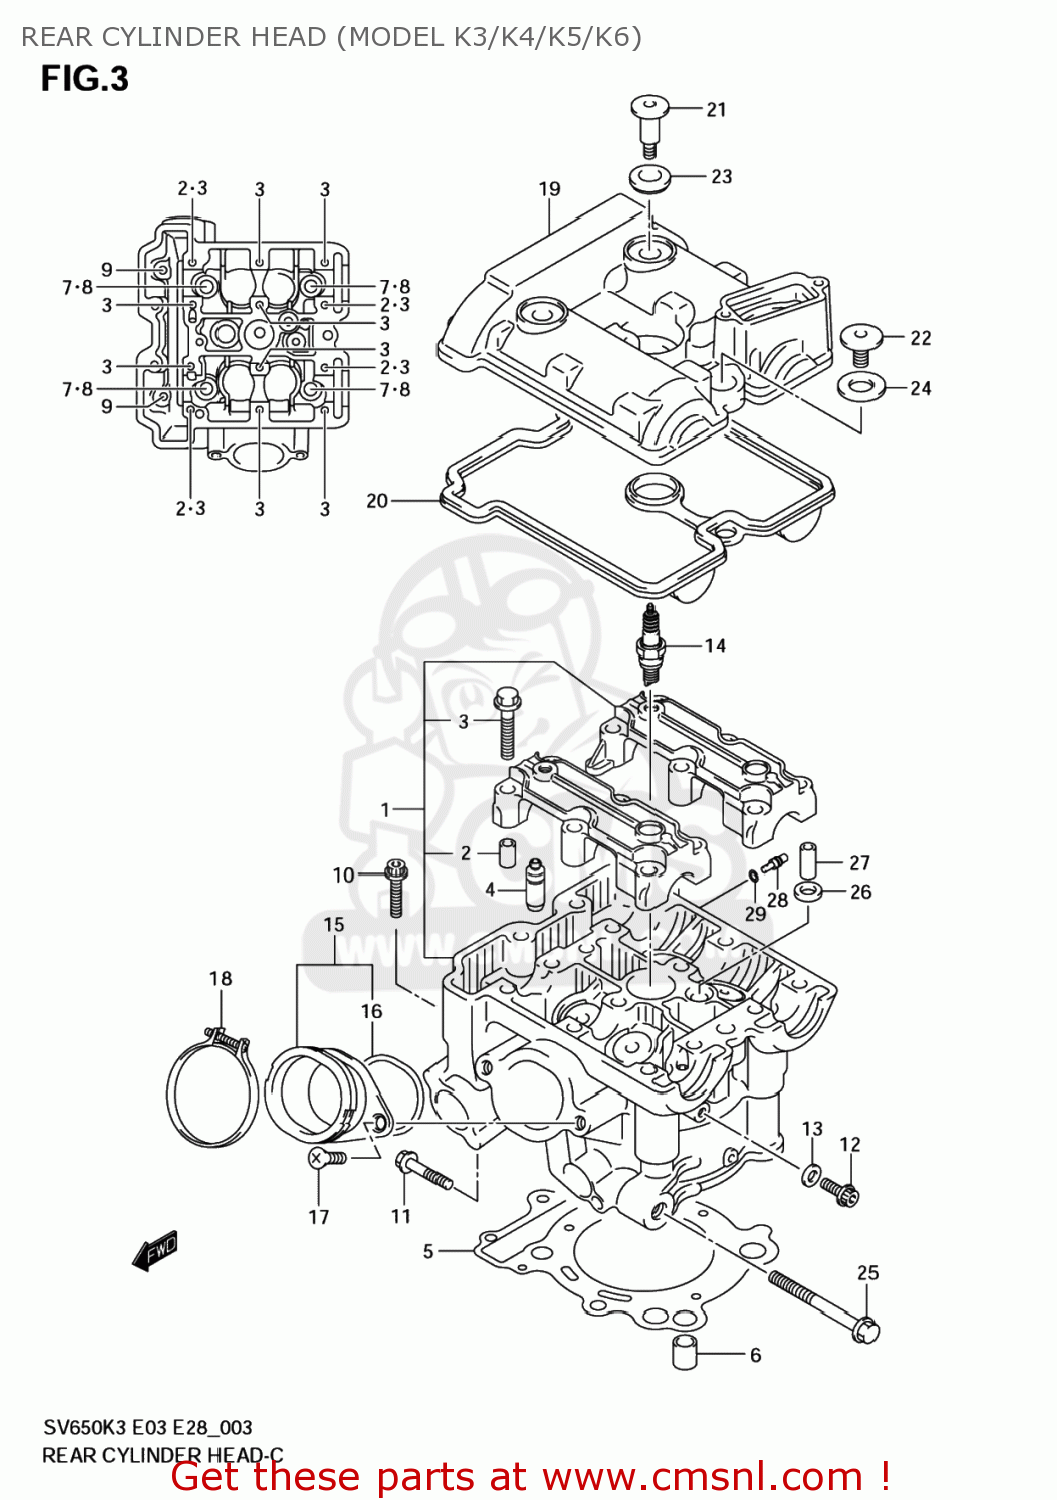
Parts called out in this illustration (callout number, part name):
1	HEAD ASSY,CYLINDER RR
2	PIN(6.2X8X11)
3	BOLT(6X39)
4	GUIDE,VALVE
5	GASKET,CYLINDER HEAD (NAS)
6	PIN
7	WASHER(10.5X19X2)
8	BOLT(10X160)
9	BOLT(6X70)
10	BOLT
11	BOLT
12	BOLT
13	GASKET(5.8X13X1.2) (NAS)
14	PLUG,SPARK(CR8E)
15	PIPE ASSY,INTAKE RR
16	O RING(D:2.4,ID:47X42)
17	SCREW ,6X16
18	CLAMP
19	COVER,CYLINDER HEAD RR
20	GASKET,CYLINDER HEAD COVER (NAS)
21	BOLT(7X17.5)
22	BOLT(7X31)
23	WASHER(10.6X25.5X2.3)
24	CUSHION,HEAD COVER BOLT
25	BOLT(10X110)
26	GASKET,2ND AIR PASSAGE (NAS)
27	PIN(6.2X8X16)
28	JET(8)
29	O RING(D:1.2,ID:4)
